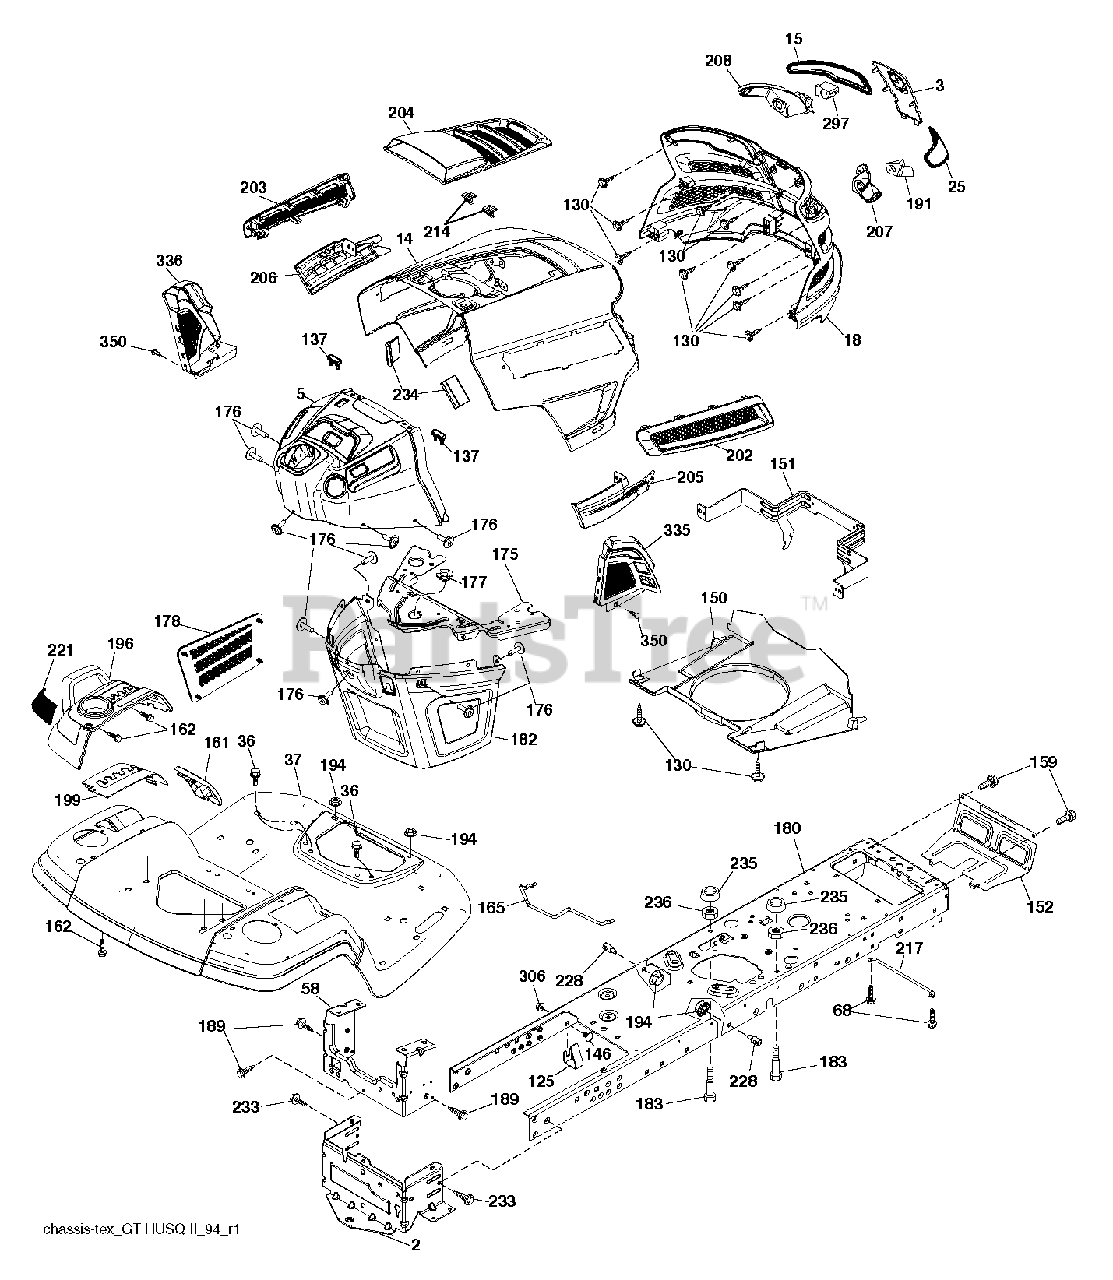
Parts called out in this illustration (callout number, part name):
2	DRAWBAR.LOWER.2PC.18/22
3	APPLIQUE.SUBASM.GT.HUSQ.II
5	DASH.HUSQ2.SM.E.NC.HR.CHG.498
14	HOOD.ASM.HUSQVARNA.GT.TEX.ORAN
15	LENS.HEADLIGHT.LH.GTII.2011
18	GRILLE.SUBSTRATE.2011.
25	LENS.HEADLIGHT.RH.GTII.2011
36	SCREW 5/16"
37	FENDER.PNT.TX.GT.CH/FW/DL.HUSQ
58	DRAWBAR.UPPER.2PC,LRG.FENDER
68	SCREW LT
125	CLIP.FUEL.LINE
130	SCREW.#10 X 0.750.BOS
137	BUMPER DASH
146	BOLT.RDHD.SHT.SQNK.3/8-16X5/8
150	AIR.DUCT.GTV.BLACK
151	BRACKET.PIVOT.HOOD.GT.HUSQ.II
152	SHIELD.BROWNING.PNT.GT.V2
159	SCREW, 3/8-16X3/4
161	CONSOLE.WINDOW.FUEL.HUSQ.GT
162	SCREW.HI-LO.CONSOLE
165	SUPPORT.TANK.REAR.B/TE
175	PLATE.CROSSMEMBER.HUSQ
176	SCREW.#10-24X5/8.RN.QU
177	BUSHING, STEERING
178	CARGO.ASM.NET.TXGT.W/C
180	CHASSIS.TEX.BOLTED
182	DASH.LOWER.COMMON.12V.ADAPTOR
183	BOLT.5/16-18X1-1/4 FULL THD
189	SCREW
191	INSERT.REFLECTIVE.RH.HUSQ.GTII
194	NUT LOCK HEX FLANGE 5/16-18
196	CONSOLE.ASM.DECKLIFT.HUSQGT.DL
199	PLATE.DECK.LIFT.HUSQVARNA.GT
202	VENT.SIDE.RH.GT.HUSQ.II.
203	VENT.SIDE.LH.GT.HUSQ.II.498
204	VENT.TOP.HUSQ.GT2
205	SIDE.TRIM.RH.GT.HUSQ.II
206	SIDE.TRIM.LH.GT.HUSQ.II.GRAY
207	BEZEL LIGHT.RH.GT.II.MYLAR
208	BEZEL LIGHT.LH.GT.II.MYLAR
214	CLIP.RETAINER.TINNER.
217	ROD.PIVOT.HOOD
221	REFLECTOR.LH.TEX GT HU
228	STUD.FASTNER.W/ANTI-ROTATE
233	BOLT.SHOULDER
234	BUMPER.HOOD.TEX.HUSQVARNA
235	SPACER FENDER
236	NUT.CENTERLOCK.5/16-
297	INSERT.REFLECTIVE.LH.HUSQ.GTII
306	NUT LOCK FLG 3/8-16 UNC
335	COVER.LOWER.DASH.RH.BLACK
336	COVER-LH.LOWER.DASH.GT2.BLACK
350	CLIP.X-MAS.TREE
